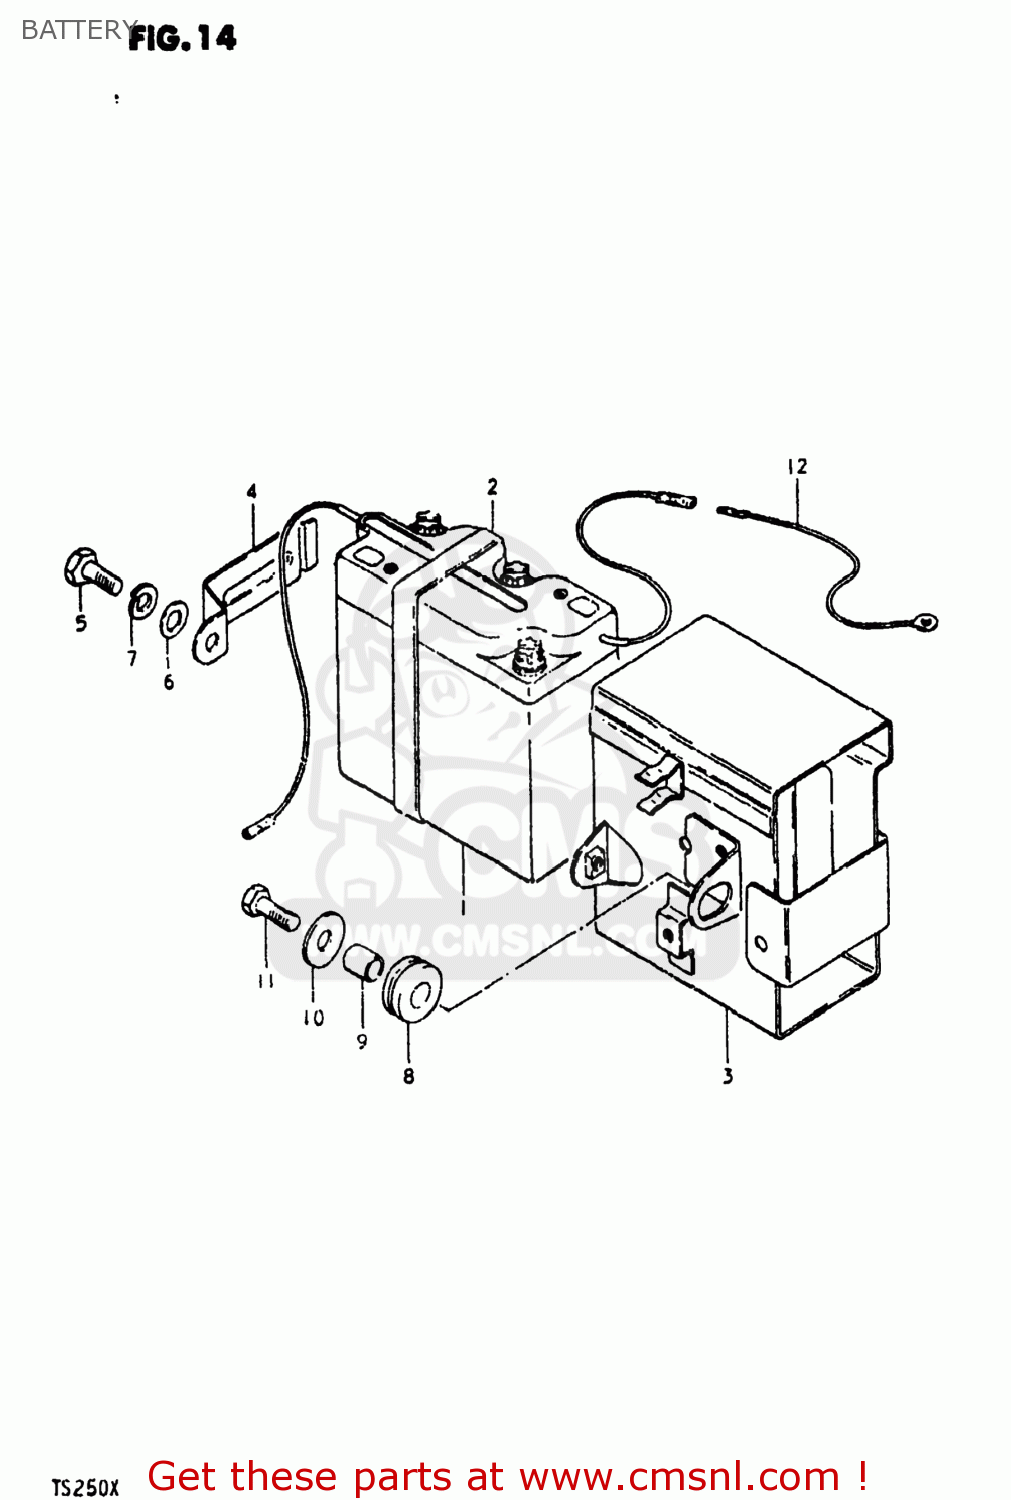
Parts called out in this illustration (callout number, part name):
1	BATTERY(6N4B-2A,6V4.2AH)
2	PROTECTOR,BATTERY
3	HOLDER,BATTERY
4	PLATE,BATTERY HOLDER
5	SCREW(6X10)
6	WASHER
7	LOCK WASHER
8	CUSHION
9	SPACER (7X9X7)
10	WASHER (6.5X20X1.2)
11	SCREW
12	LEAD WIRE
